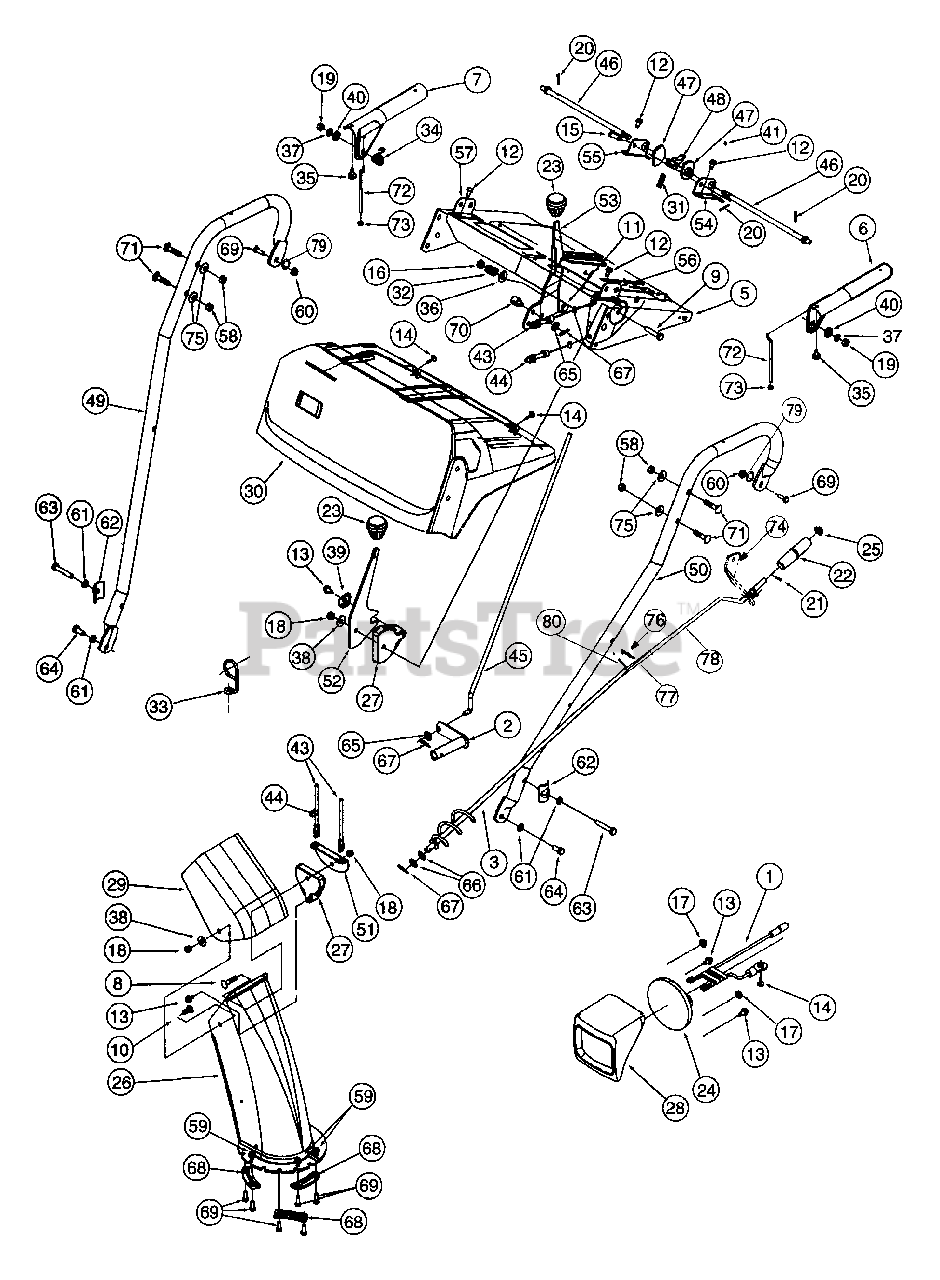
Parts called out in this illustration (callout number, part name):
1	Harness for Headlight
2	Shift Arm Assembly
6	Handle Assembly Engagement (L.H.)
7	Handle Assembly Engagement (R.H.)
8	Carriage Bolt 5/16-18 x 1.50
9	Hex Bolt 5/16-18 x 1.5
10	Carriage Bolt 5/16-18 x.75
11	Hex Screw 3/8-24 x 1.5
12	Hex Washer Hd. TT Screw 1/4-20 x 0.5"
13	Hex AB Tap Screw 1/4 x .62
14	Hex B-Tapp Screw #10-16 x.62
15	Clevis Pin
16	Hex Ins. Lock Nut 3/8-24
17	Self Threading Nut
18	Lock Nut 5/16-18
19	Hex Nut
20	Cotter Pin
21	Roll Pin
22	Chute Crank Knob
23	Shift Knob
24	Headlight
25	Push Cap
26	Lower Chute
27	Cable Guide
28	Headlight Bezel
29	Upper Chute
30	Handle Panel
31	Compression Spring
32	Compression Spring
33	Cable Control Wire
34	Torsion Spring
35	Rubber Bumper
36	Bell Washer .380 x .880 x .062
37	Lock Washer 5/16 I.D.
38	Washer 5/6 I.D.
39	Special Washer
40	Special Washer
41	Grease
43	Chute Deflector Control Cable
44	Chute Deflector Cable w/Clip
45	Shift Rod
46	Cam Rod
47	Cam Handle Lock
48	Pawl Handle lock
58	Hex Nut 5/16-18 Thd.
59	Hex Range Locked Nut 1/4-20 Thd.
60	Hex Nut 1/4-20
61	Lock Washer 5/16
62	Handle Tab
63	Hex Bolt 5/16-18 x 1.75 Gr.5
64	Hex Bolt
65	Flat Washer 5/16
66	Flat Washer 3/8 x .738 x .063
67	Hairpin Clip
68	Chute Flange Keeper
69	Hex Bolt 1/4-20 x 0.75" Gr.5
70	Ferrule
71	Carriage Bolt 5/16-18 x 1.50
72	Z Fitting
73	Hex Nut #10-24
75	Cupped Washer .340 I.D. x .872 O.D.
76	Hairpin Clip
77	Spacer
79	Bell Washer
80	Roll Pin
